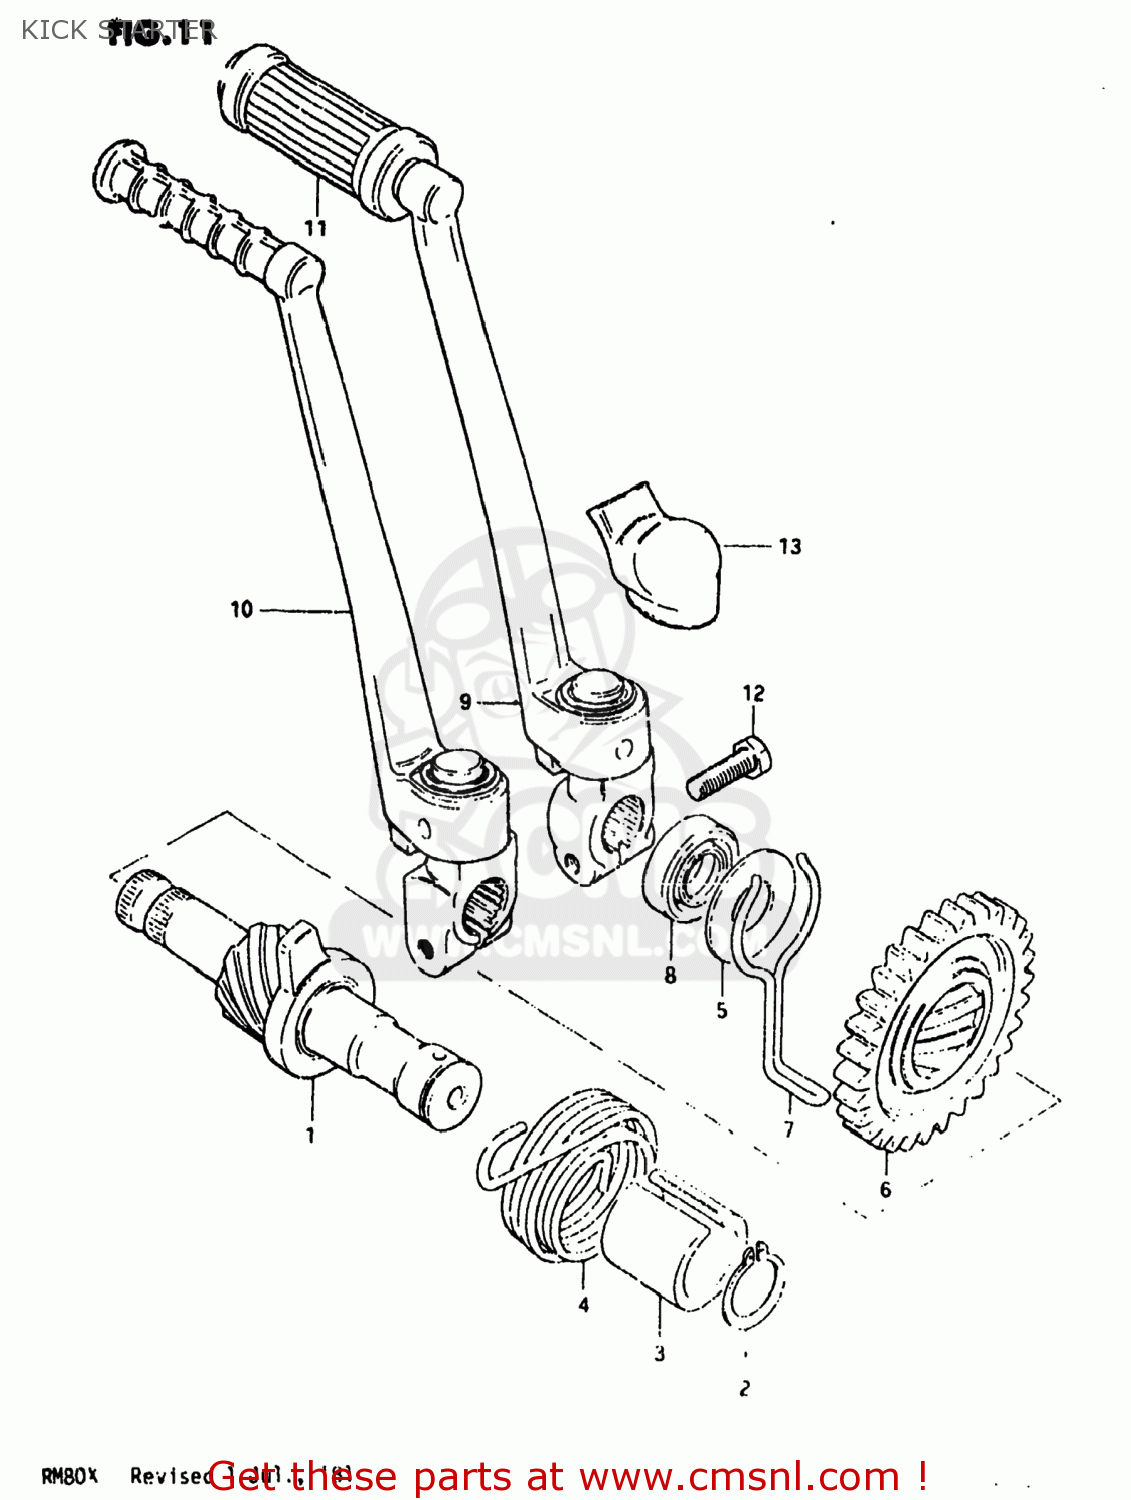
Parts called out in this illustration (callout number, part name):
1	SHAFT,KICK STARTER
2	CIRCLIP,16MM
3	GUIDE,KICK STARTER SFT SPRING
4	SPRING
5	WASHER
6	GEAR,KICK STARTER DRIVE(NT:30)
7	RETAINER,SNAP
8	SEAL,OIL(14X24X6)
9	LEVER ASSEMBLY,KICK STARTER
10	LEVER ASSY,KICK STARTER
11	RUBBER,KICK STARTER PEDAL
12	BOLT
13	COVER,KICK STARTER PEDAL
